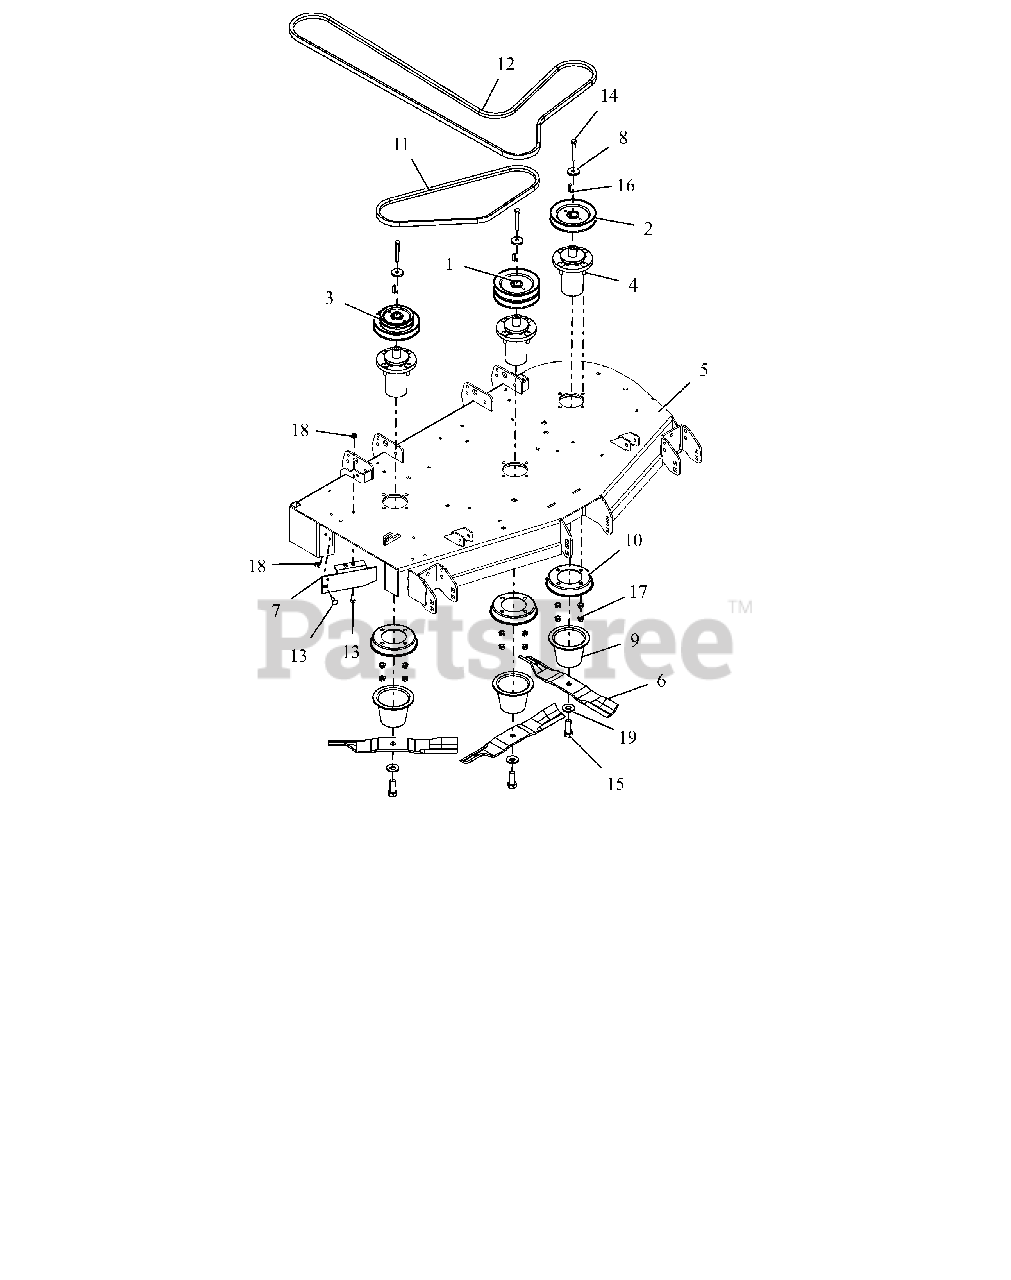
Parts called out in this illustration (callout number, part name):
1	PULLEY, DOUBLE-1"ID X 5.75"OD
2	PULLEY, V-1" ID X 5.75" OD
3	PULLEY, DBL-1"IDX5.75"&4.25"OD
4	ASM, MAINT FREE ALUM SPINDLE
5	DECK, PT148 W/SAFETY DECALS
6	BLADE, 16.19" MOWER (HI-LIFT)
7	44"-48" SIDE DISCH BAFFLE -RED
8	RETAINER, SHEAVE
9	GUARD, SPINDLE LOWER
10	GUARD, SPINDLE TOP
11	V-BELT, B-COGGED
12	V-BELT, B RAW EDGE EPDM
13	@BLT-RDHDSQNK .31-18X1.00 G5YZ
14	BLT-HEX .38-16X2.75 GR8 YWZC
15	BLT-HEX .62-18X1.75 GR8 YWZC
16	KEY, SQ .25X.25X1.00 RC 40-50
17	NUT-LK-CTR-FLG .38-16 YWZC
18	@NUT-LK-NYL-FLG .31-18 YWZC
19	WSHR-BLVL .669X1.535X.138
